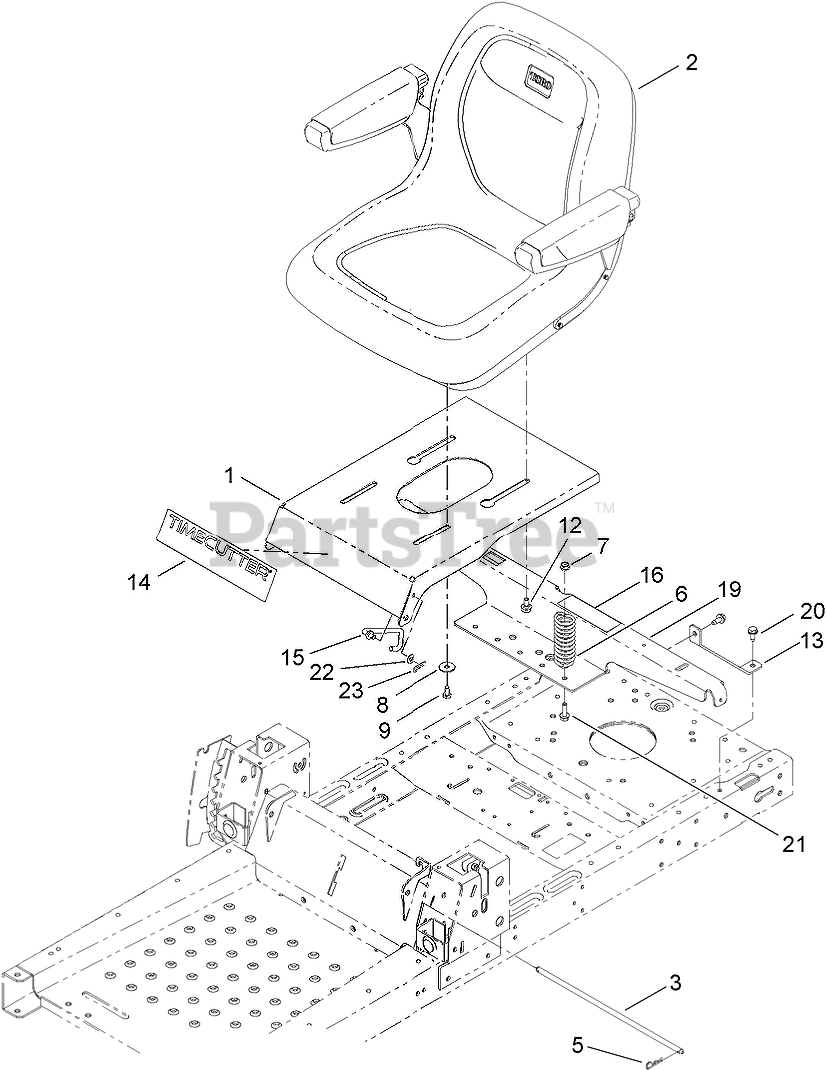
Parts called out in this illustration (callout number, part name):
1	PAN-SEAT
2	SEAT-18 Inch
3	ROD-PIVOT, NARROW
5	PIN-COTTER
6	SPRING-COMPRESSION
7	NUT-HF, NI
8	WASHER-PIVOT
9	SCREW-HH
12	BOLT-SHOULDER
13	SUPPORT-TANK, REAR
14	DECAL-TIMECUTTER
15	STOP-SEAT
16	DECAL-SERVICE, CE
19	SUPPORT-POD
20	SCREW-HWHTF
21	SCREW-HHF
22	WASHER-PLAIN
23	PIN-COTTER
